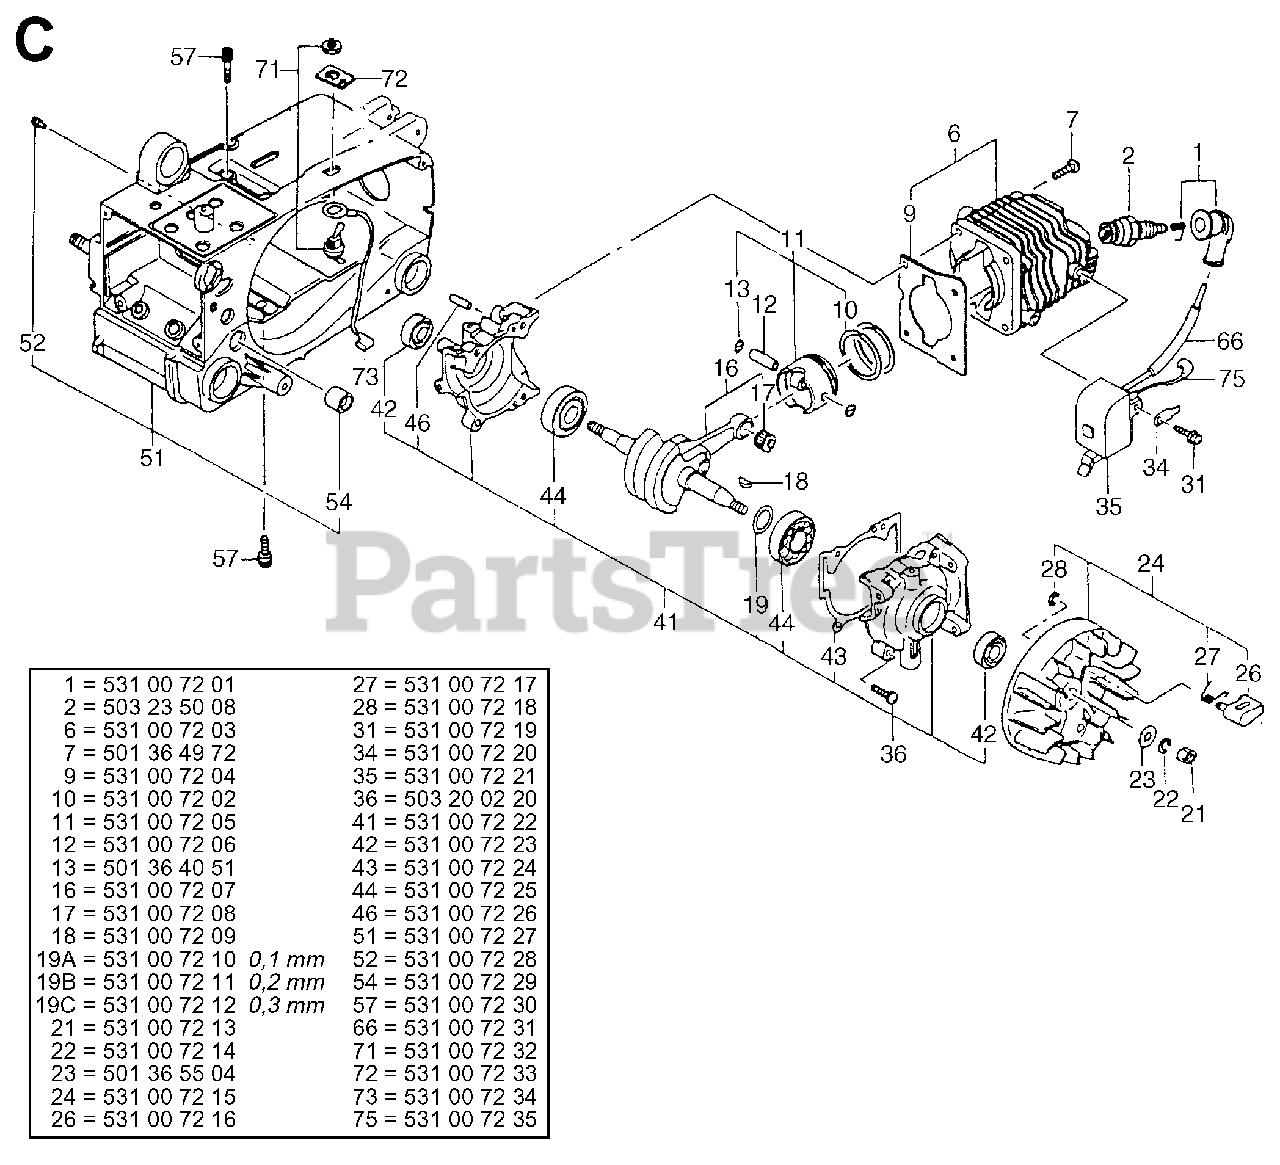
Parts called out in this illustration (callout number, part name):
1	SPARK PLUG CONNECTION
2	SPARK PLUG CJ8 NLA
10	PISTON RING
12	PISTON BOLT
16	CRANKSHAFT
17	NEEDLE BEARING
19A	WASHER
19B	WASHER
19C	WASHER
28	RETAINING RING
35	IGNITION COIL
41	CRANKCASE
51	CRANKCASE
66	PROTECTOR
71	STOP SWITCH
